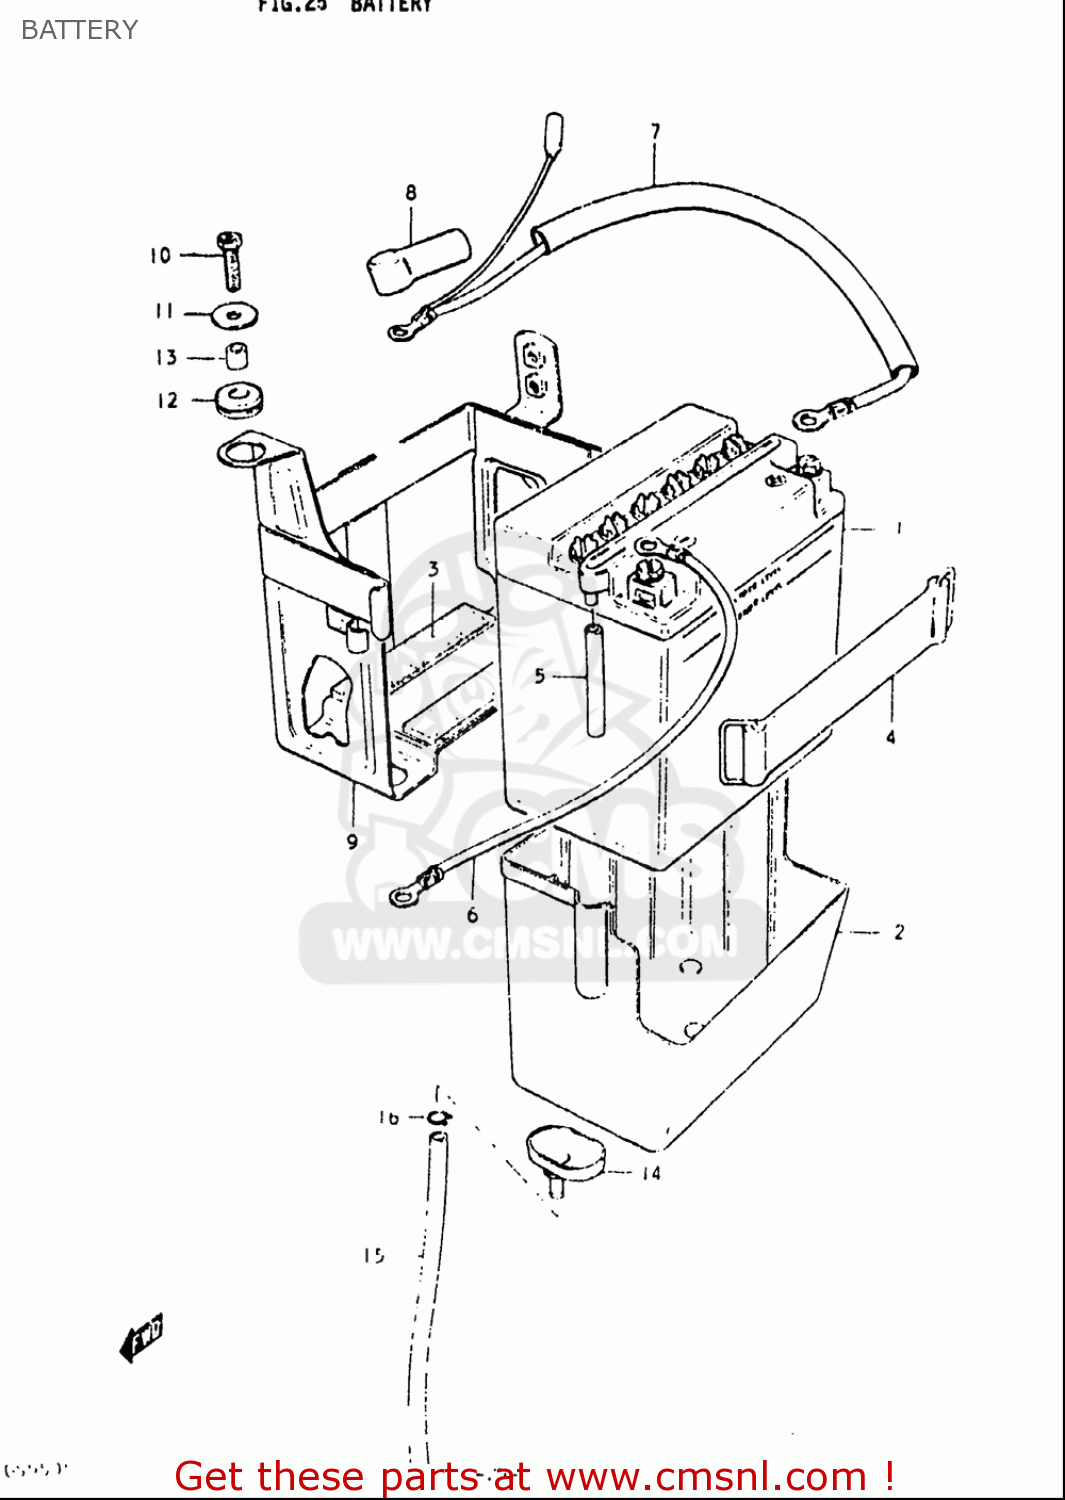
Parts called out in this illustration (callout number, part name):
1	BATTERY ASSY (12V)
3	PROTECTOR(170X95X3.0)
4	BAND
5	HOSE,BATTERY EXHAUST(L:780)
6	LEAD WIRE,BATTERY(-)
7	CORD,BATTERY
8	CAP,TERMINAL
10	BOLT(6X20)
11	WASHER(6.5X20X1.6)
12	CUSHION
13	SPACER(6.1X9X7.5)
14	FUNNEL,BATTERY EXHAUST
15	HOSE,BATTERY EXHAUST(L:780)
16	CLIP
